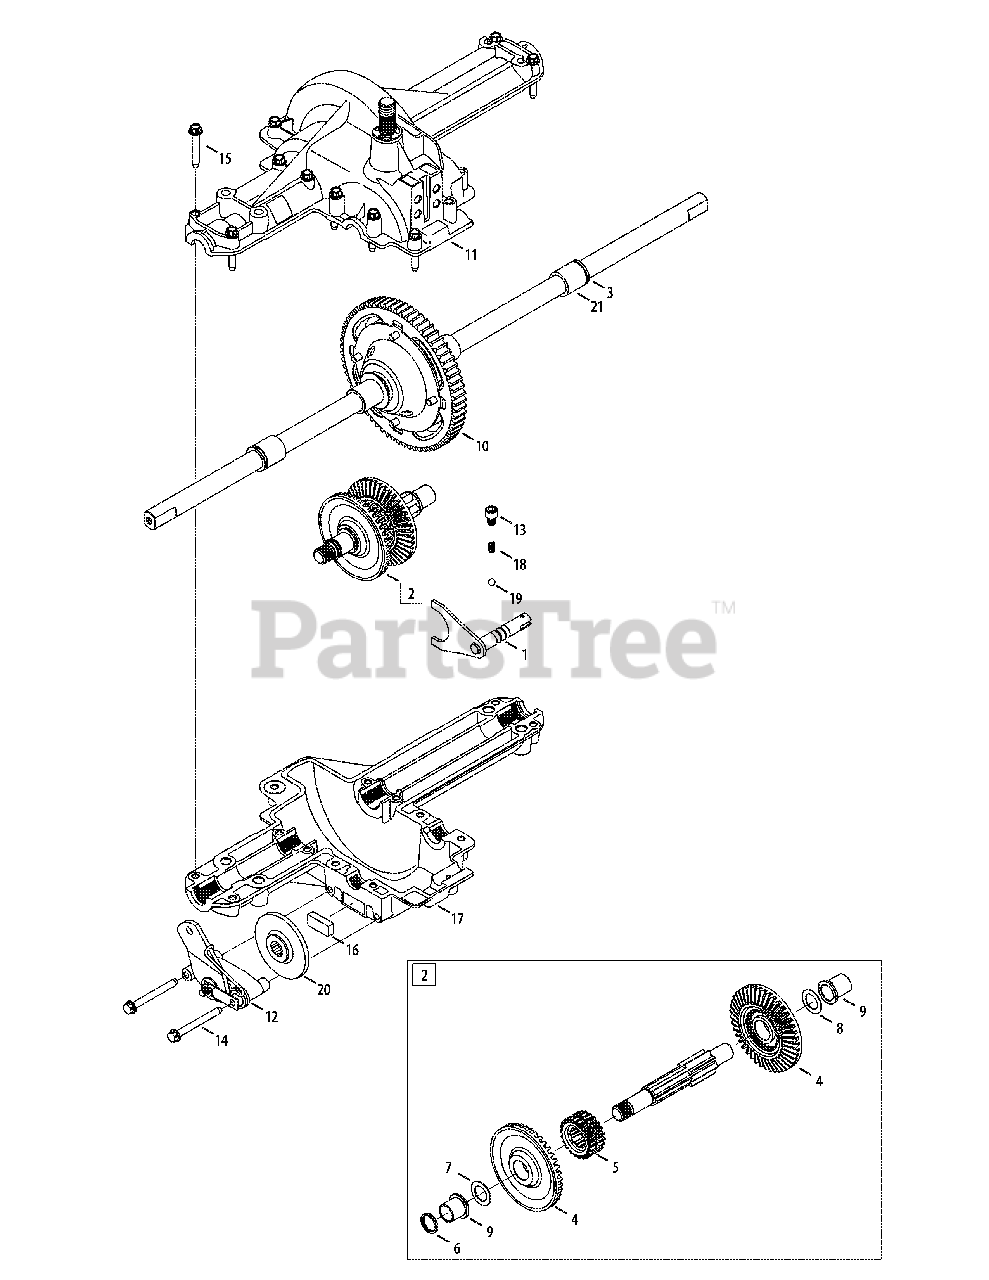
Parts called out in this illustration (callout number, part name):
1	Detent Shaft Ass’y
2	Drive Shaft
3	Oil Seal .750 x 1.00 x .125
4	Bevel Gear, 42 tooth spline
5	Single Speed Clutch Collar
6	Seal .625 x .812 x .094
7	Flat Washer 5/8 ID x 1.0 OD x .030
7	Flat Washer 5/8 ID x 1.0 OD x 0.040
7	Flat Washer 5/8 ID x 1.0 x .020
7	Thrust Wash. 5/8" ID x 1.0" OD x .035
7	Thrust Wash. 5/8" ID x 1.0" OD x .025
8	Flange Bearing 5/8 x 3/4
9	Flange Bearing 5/8 x 15/16
10	Differential Assembly
11	Upper Housing
12	Brake Assembly
13	Self-Tap Scr. 5/16-18 x .375 Vis
14	Self-Tap Scr. 1/4-20 x 2.375 Vis
15	Self-Tap Scr. 1/4-20 x 1.625 Vis
16	Brake Puch
17	Lower Housing
18	Com pression Spring
19	Ball Detent .250 Dia.
21	Sleeve Bearing 3/4 ID x 1.0
